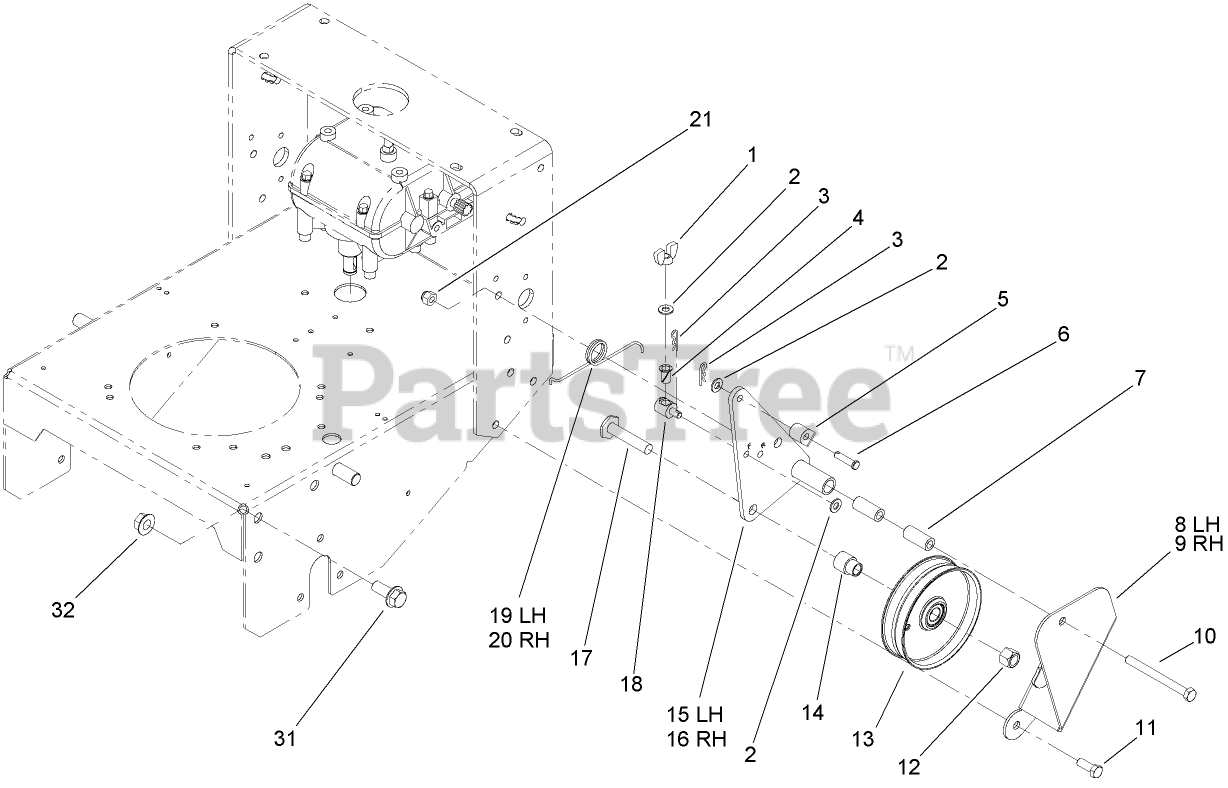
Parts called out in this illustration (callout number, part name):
1	NUT-WING
2	WASHER-PLAIN
3	PIN-COTTER
4	BUSHING-NYLON
5	FITTING-ROD
6	PIN-CLEVIS
7	SPACER-PIVOT, IDLER
8	BRACKET-SUPPORT, LH
9	BRACKET-SUPPORT, RH
10	SCREW-HH
11	SCREW-HH
12	NUT-LOCK, NI
13	PULLEY-IDLER
14	SPACER-PULLEY
15	BRACKET-IDLER, LH
16	BRACKET-IDLER, RH
17	SCREW-LEVELER
18	FITTING-ROD
19	SPRING-TORSION, LH
20	SPRING-TORSION, RH
21	NUT-LOCK, NI
31	SCREW-HHF
32	NUT-HF
